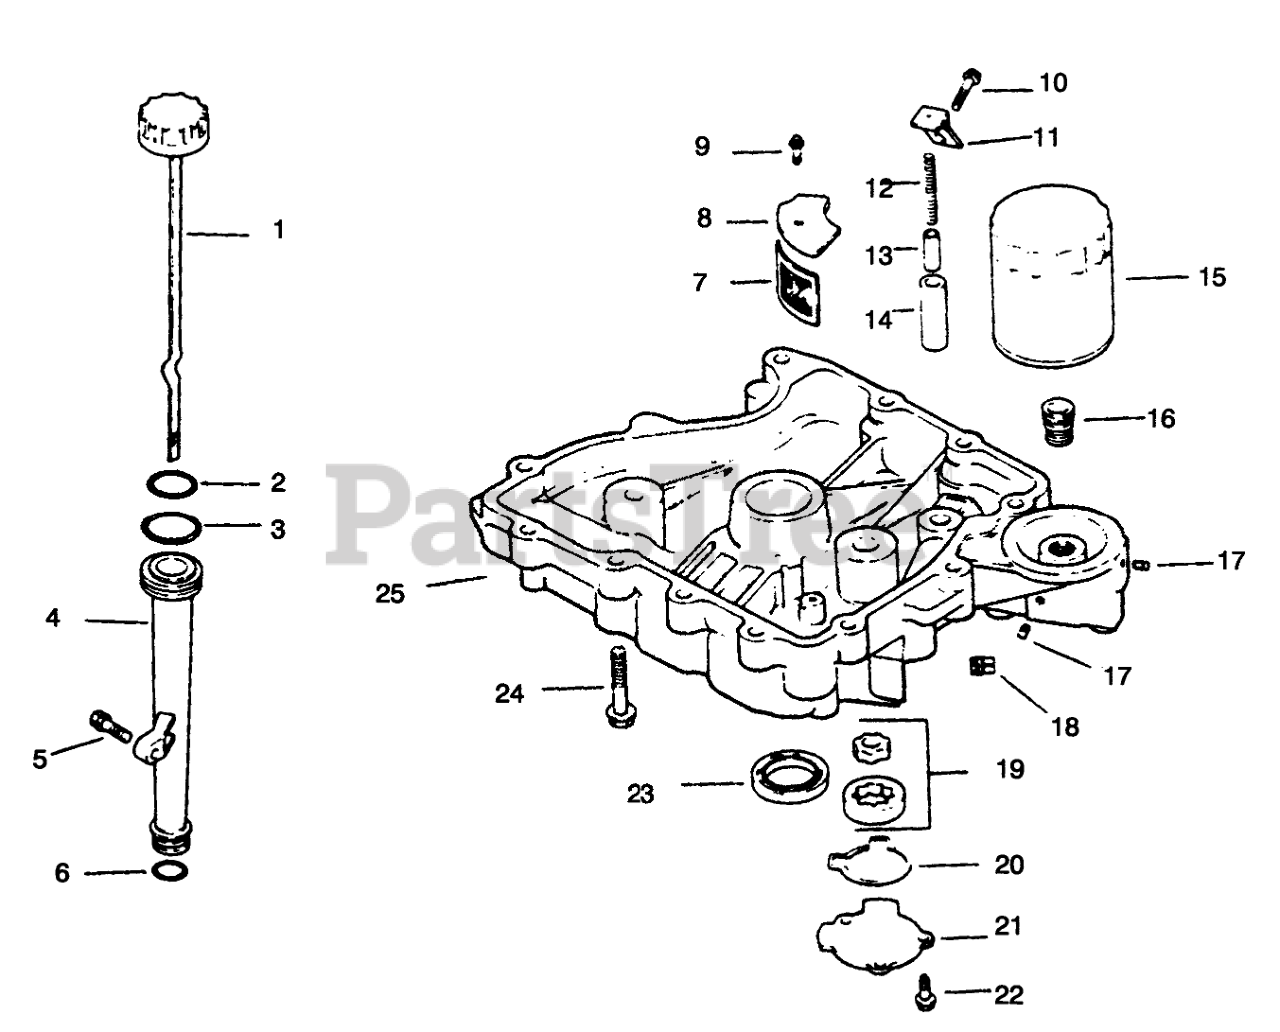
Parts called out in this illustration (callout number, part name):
1	Dipstick INC 2-3
2	"O"Ring
3	"O"Ring
4	Tube-Oil Fill
5	Screw
6	"O"Ring
7	Screen-Oil Pickup
8	Cover-Oil Screen
9	Screw
10	Screw
11	Bracket-Oil Pump Relief
12	Spring-Oil Relief Valve
13	Piston-Oil Relief Valve
14	Body-Oil Relief Valve
15	Filter-Oil
16	Adapter-Oil Filter
17	Plug-SH 1/8
18	Plug
19	Pump-Oil
20	"O"Ring-Pump Cover
21	Cover-Oil Pump
22	Screw
23	Seal-Crankshaft
25	Pan-Oil
